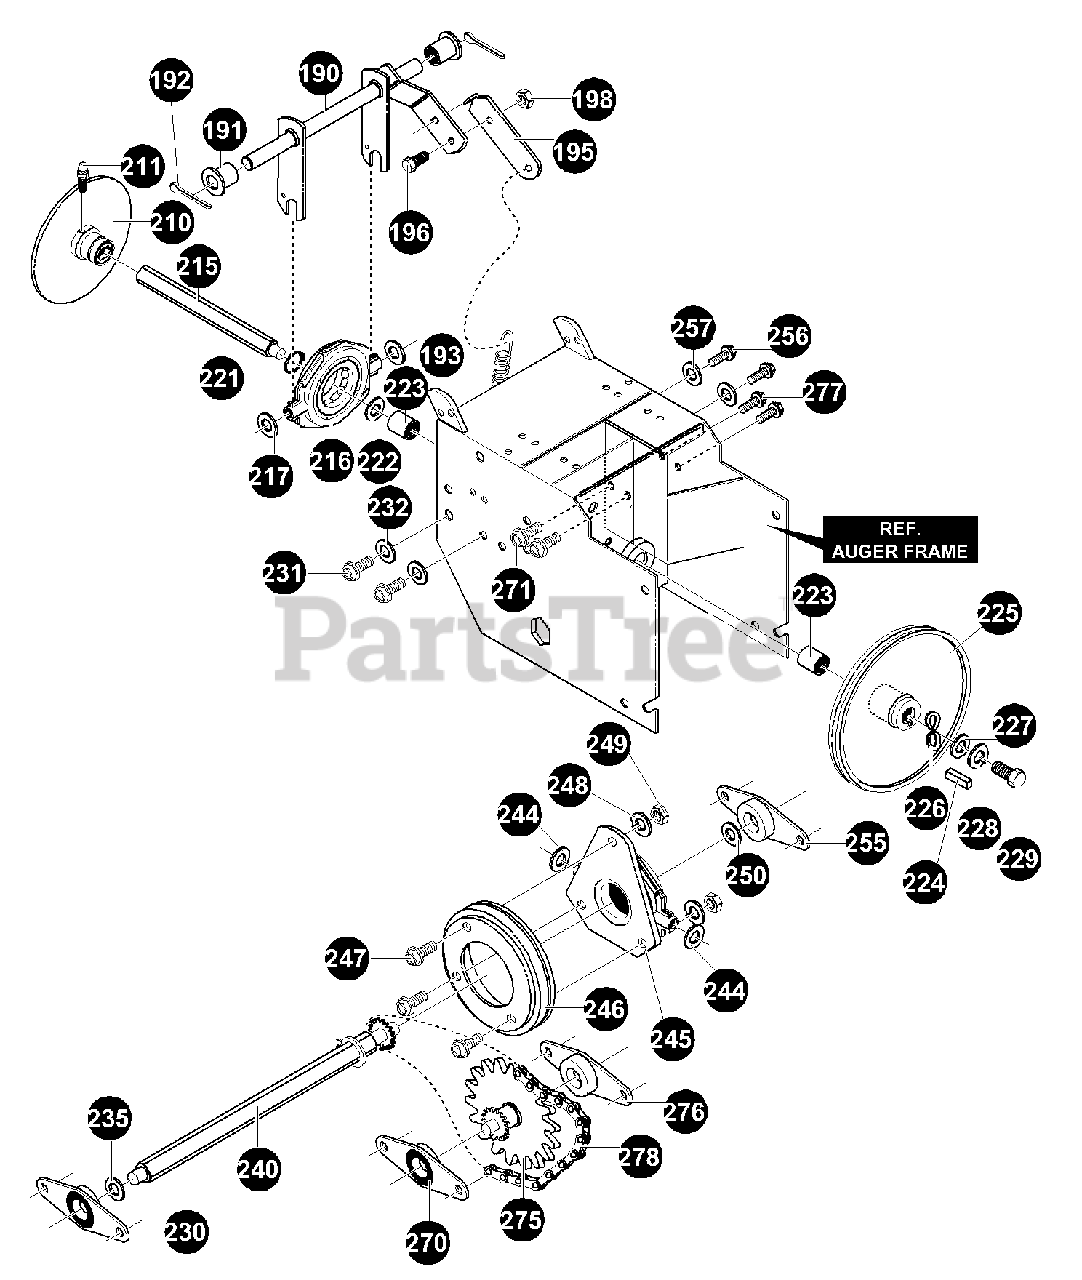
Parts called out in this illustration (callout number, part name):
190	LEVER, ASSY TRACTION CLUTCH
191	BEARING, FLANGED
192	COTTER PIN .125 DIAX1.00LG
193	SPRING, RETURN
195	LEVER, SPRING TRAC CLUTCH
196	SCREW, 1/4-20X.63
198	NUT, 1/4-20 REGHEXCTRLK
210	DISC, ASSY FRICTION WHEEL
211	ZERK, GREASE
215	SHAFT, HEX TRACTION
216	BEARING, TRUNION
217	FLATWASHER, .680X1.12X.060
221	RING, RETEX 1.16X.05TRU
222	FLATWASHER, .680X1.12X.060
223	BEARING, BALL 6203-2AA-C3
224	KEY, SQUARE .18SQX,63LG
225	PULLEY, V3L 6.50X.56
226	WASHER, WAVE .675X1.00X.020
227	FLATWASHER, .281X1.00X.063
228	WASHER, RSPTLK .263X.49X.07
229	SCREW 1/4-20X.75
230	BEARING & RETAINER ASSY
231	SCREW 5/16-18X.50 WAHHTAP
232	WASHER, HVSPTLK .328X.60X.09
235	WASHER, SP .502X.75X.0605
240	SHAFT & SPROCKET ASSY
244	FLATWASHER .505X1.00X.06
245	BEARING, TRUNION CLUTCH
246	WHEEL, ASSY FRICTION DISC
247	SCREW, 1/4-20X.63
248	WASHER, RGSPTLK .263X.49X.07
249	NUT, 1/4-20 REGHEX
250	WASHER, SP .502X.75X.0605
255	BEARING & RETAINER ASSY
256	SCREW 5/16-18X.50 WAHHTAP
257	WASHER, HVSPTLK .328X.60X.09
270	BEARING & RETAINER ASSY
271	SCREW 5/16-18X.50 WAHHTAP
275	JACK, ASY #41-36T&8T W/PBRG
276	BEARING & RETAINER ASSY
277	SCREW 5/16-18X.50 WAHHTAP
278	CHAIN ROLLER #42 X 40P
